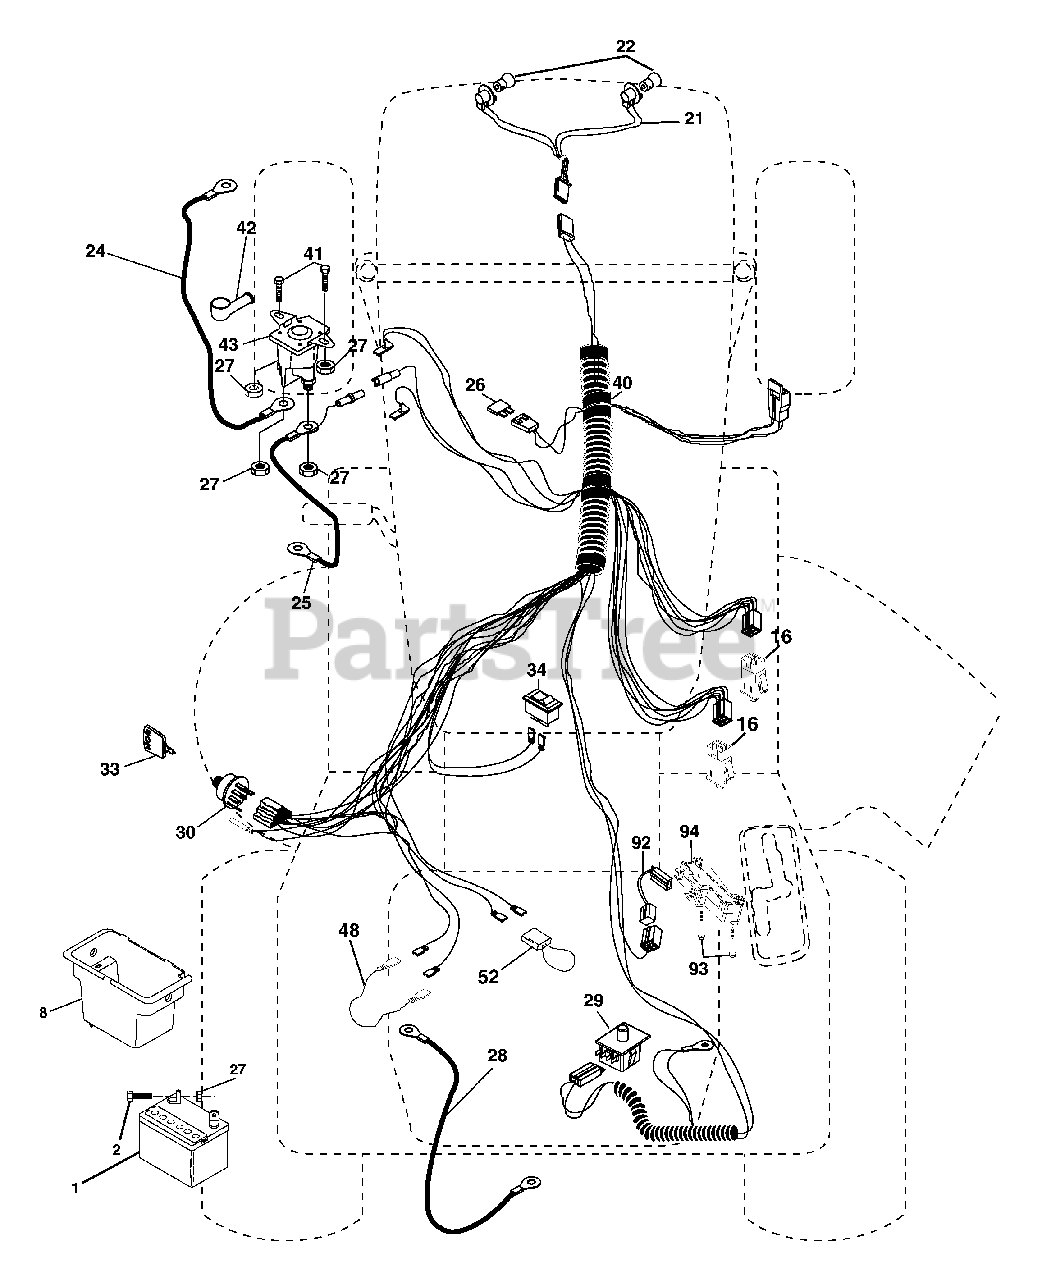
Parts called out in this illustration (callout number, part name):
1	Battery
2	Bolt Hex Hd 1/4-20 unc x 3/4
8	Box Battery
16	Switch Interlock
21	Harness Socket Light
22	Bulb, Light # 1156
24	Cable Battery
25	Cable Battery 6 Ga. Red w/16 wire 44"
26	Fuse
27	Nut Keps Hex 1/4-20 unc
28	Cable Ground 12" Blk 6 Ga.
29	Switch
30	Switch Ign
33	Key Ign Molded Generic
34	Switch Light/Reset B/B Red
40	Harness Ign
41	Bolt Fin Hex 1/4-20 unc x 1/2
42	Cover Terminal Red
43	Solenoid
45	Ammeter Rectangular
52	Protection Loop
90	Cover Terminal
92	Harness Pigtail Reverse Switch
93	Screw Plastite 10-14 x 2.0
94	Module Reverse ROS
